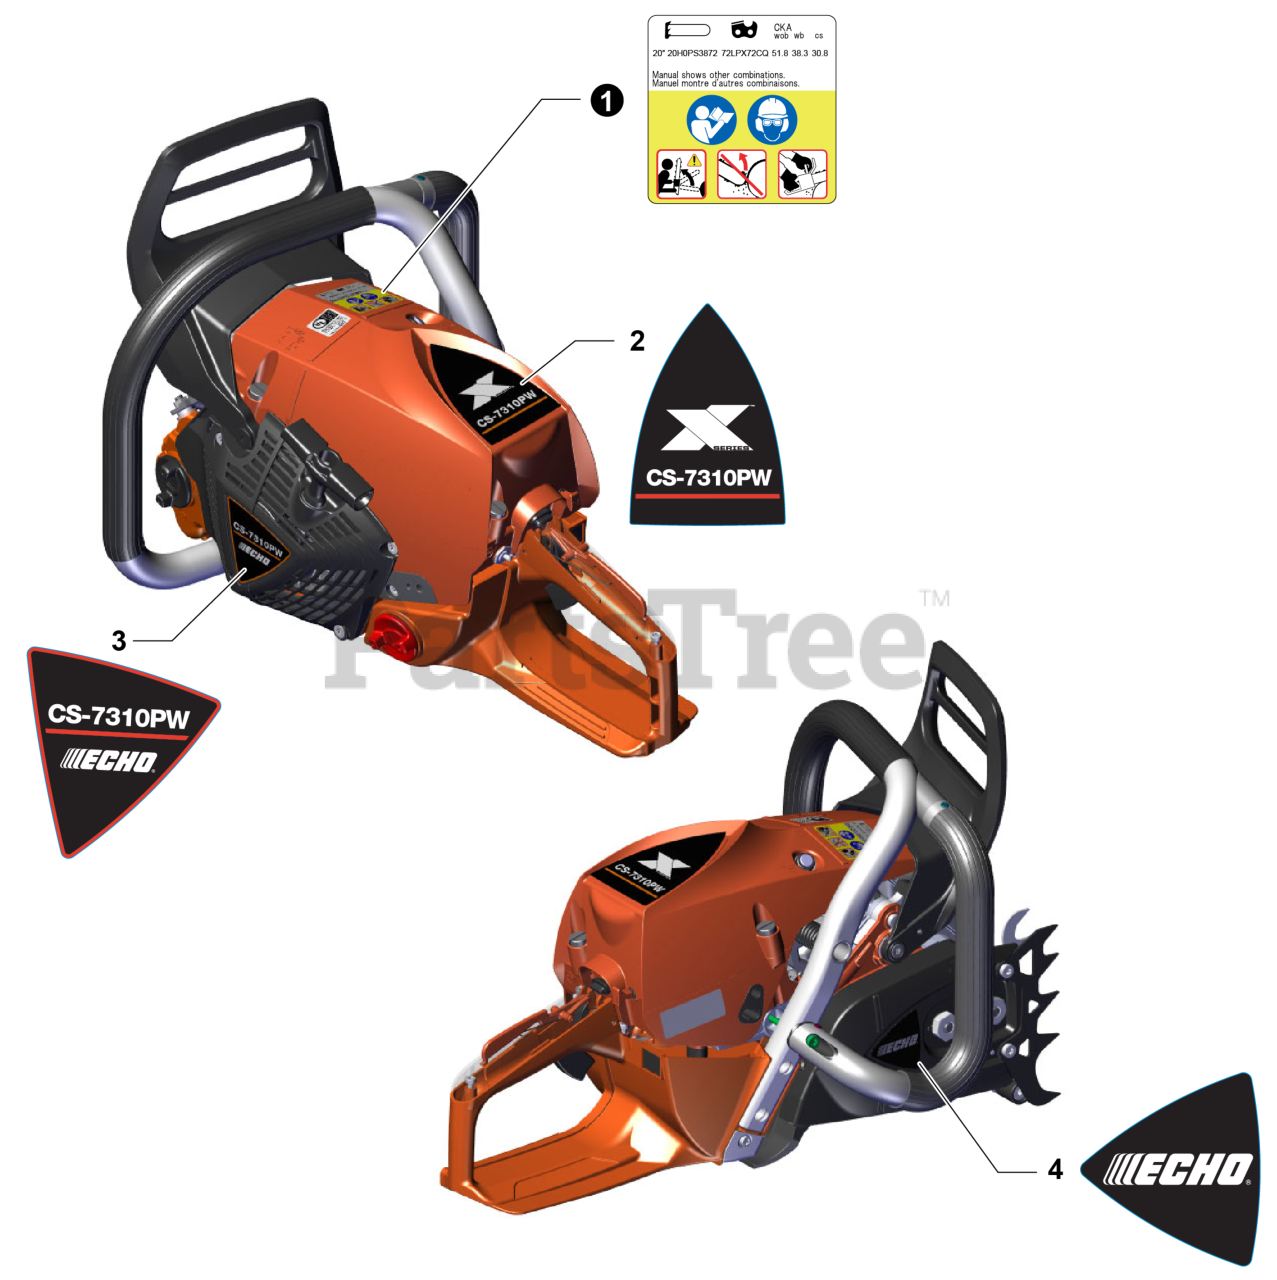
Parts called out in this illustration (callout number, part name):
1	LABEL - CAUTION - ISO
2	LABEL - MODEL CS-7310PW
3	LABEL - RECOIL STARTER
4	LABEL - ECHO
